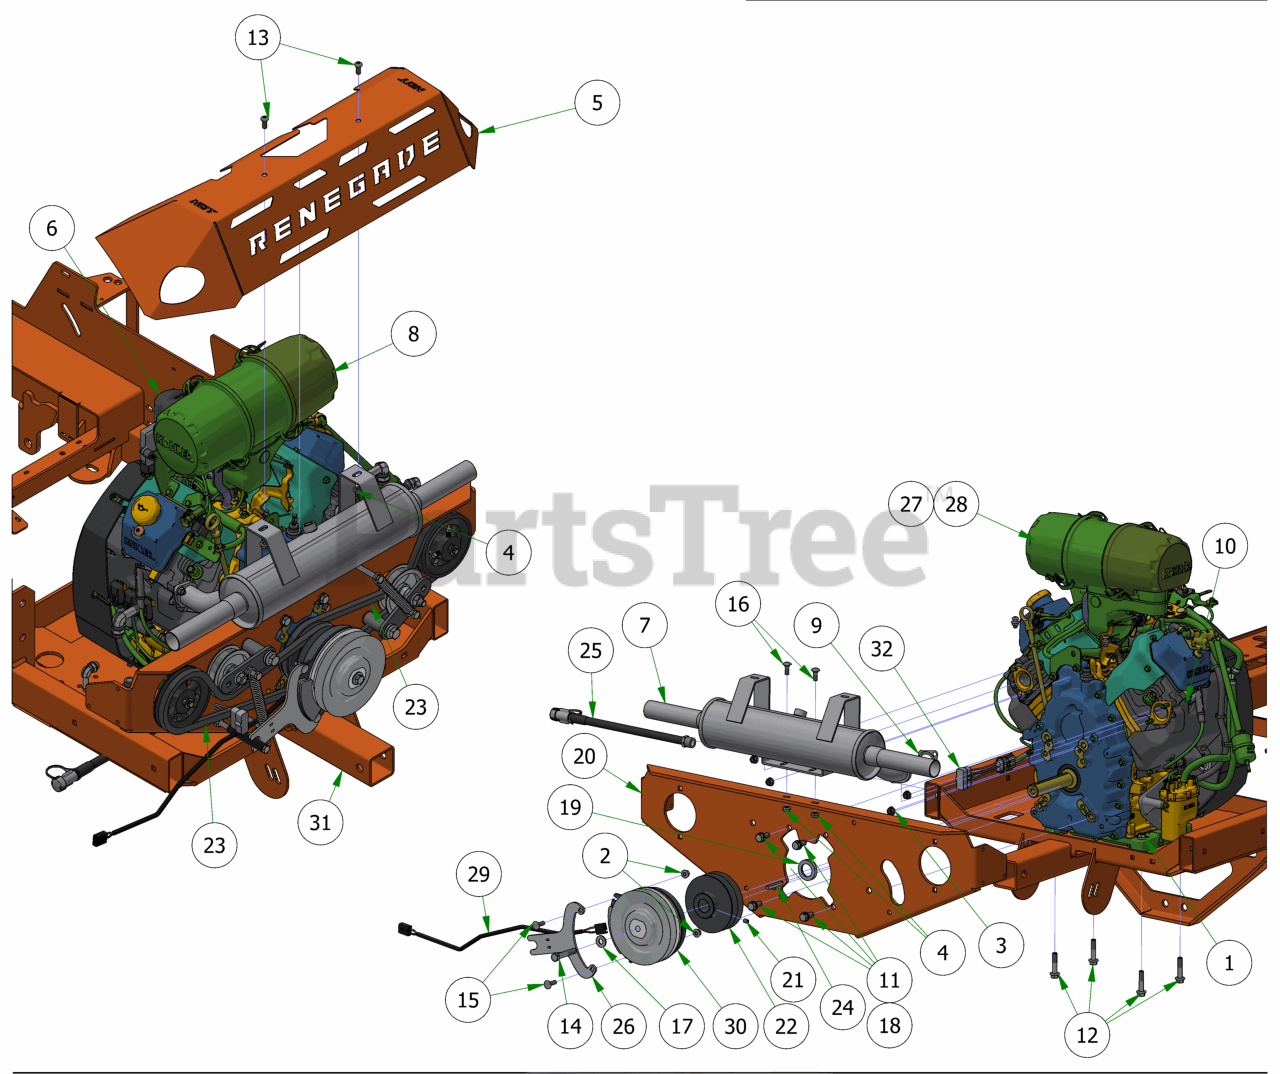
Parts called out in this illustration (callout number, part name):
1	3/8-16 HEX FLANGE TOP LOCKNUT ZINC
2	5/16-18 NYLON INSERT FLANGE LOCKNUT ZINC
3	M8 Nut Connects the 015-1012-00 and the 015-8240-00
4	5/16-18 HEX SERRATED FLANGE NUT HARD/ZINC
5	2023 Renegade Gas Muffler Cover
6	Kohler ECV/ECH980 OIL FILTER
7	KOHLER ECH980 MUFFLER
8	Kohler ECH980 Engine
9	ECV/ECH 980 MUFFLER GASKET
10	Spark Plug - Kohler ECV/ECH 980
11	7/16-14 X 1 HEX CAP SCREW (GR.5) ZINC
12	3/8-16x1-3/4 Gr5 Hex Flange Screw Zinc Clear
13	5/16-18 X 3/4 BUTTON SOCKET CAP SCREW 18-8 STAINLESS STEEL
14	7/16-20 X 2-1/2 HEX Bolt GR 8 W/ Patch
15	5/16-18 X 1 CARRIAGE BOLT (GR.8) ZINC
16	5/16-18 X 7/8 CARRIAGE BOLT ZINC
17	3/8 FLAT WASHER USS (1" OD) ZINC
18	7/16 SPLIT LOCKWASHER (GR.8) ZINC YELLOW
19	Horizontal Engine Spacer
20	Pump Plate - 2019 Horizontal Gas-Orange
21	5/16-24 X 3/8 SOCKET SET SCREW (KNURLED CUP PT) PLAIN
22	Outlaw Renegade Double V Pulley
23	2020 Renegade Pump Belt, 42.99"
24	1/4 X 2 SQ MACHINERY KEY 1018 STL PLAIN
25	Kohler 980 Oil Drain
26	2019 Outlaw Renegade Clutch Bracket
27	Canister Air Filter- Outer
28	Canister Air Filter- Inner
29	Clutch Pigtail
30	Clutch for Diesel/Vanguard
31	2019 Renegade Gas Frame - Powdercoated
32	ECH980 Wiring Harness Adapter
